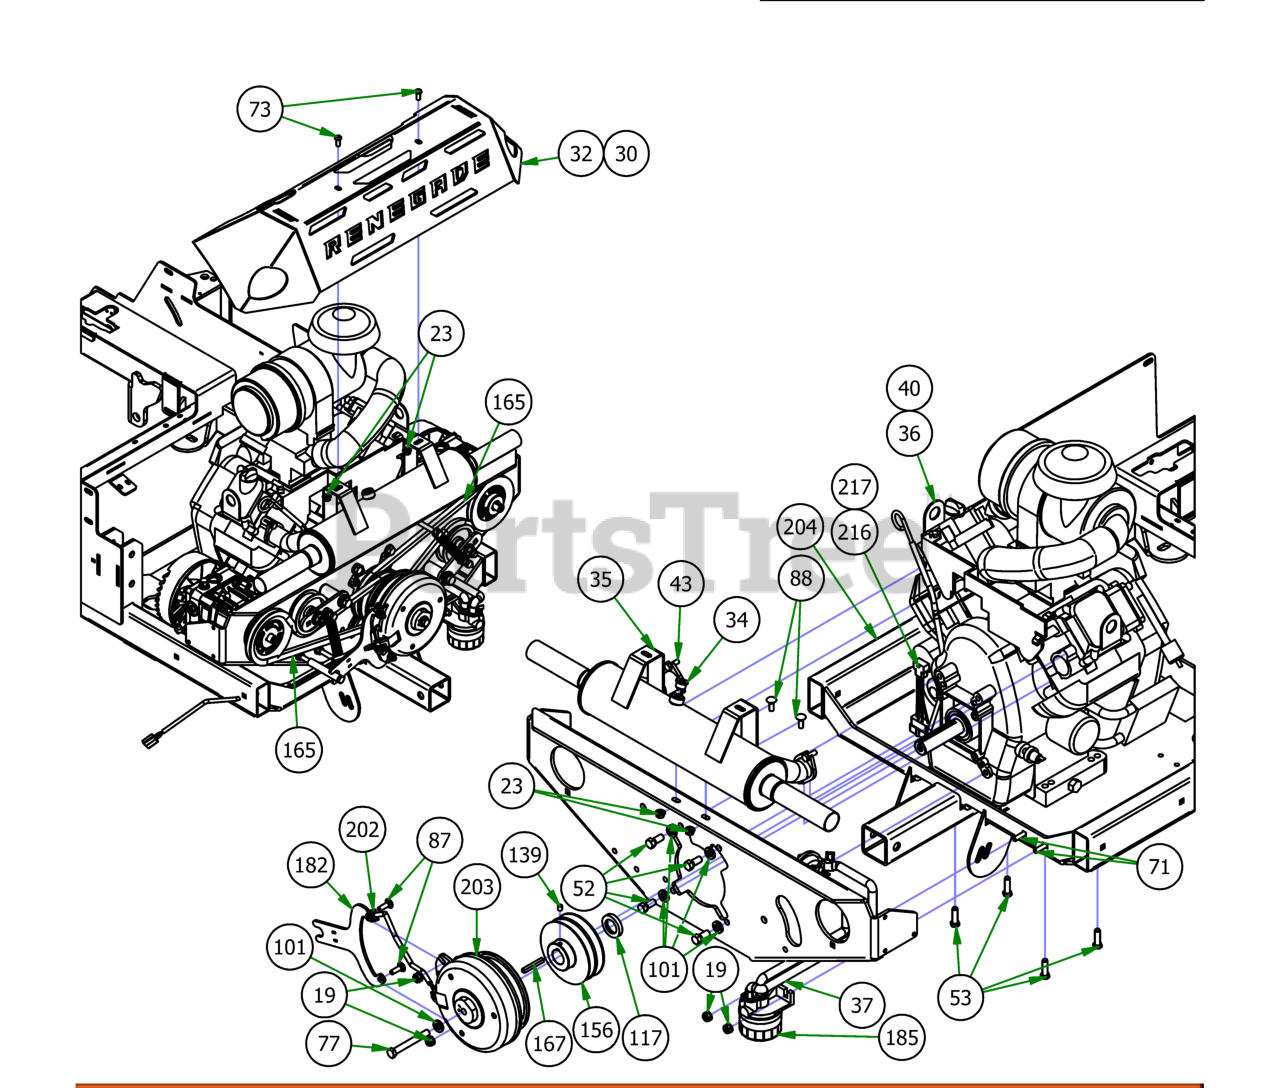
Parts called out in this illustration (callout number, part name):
19	5/16-18 Nylon Flange Nut
23	5/16" Flange Nut
30	Muffler Cover - 2019 Horizontal Gas 37 Vanguard
32	Muffler Cover - 2019 Horizontal Gas 35 Vanguard
34	O2 Sensor Plug
35	2019 Renegade Vanguard 999cc EFI Exhaust
36	Vanguard EFI 37HP 993cc Horizontal Shaft
37	Remote Oil Filter Kit For Vanguard Horizontal
40	35hp Briggs Vanguard
43	Torx Bolt-Exhaust
52	Hex Bolt - UNC (Regular Thread - Inch)
53	3/8-16 x 2 Hex/ Trilobe Horizontal Engine Bolt
71	5/16" x 1 1/4" Carriage Bolt
73	5/16" x 3/4" Button Head Bolt
77	7/16-20 x 3 1/2" Hex Head GR 8 Bolt
87	5/16" x 1" Carriage Bolt
88	5/16" x 7/8" Carriage Bolt
101	7/16" Lock Washer
117	Horizontal Engine Spacer
139	5/16-24 X 3/8 Set Screw
156	Outlaw Renegade Double V Pulley
165	2020 Renegade Pump Belt, 42.99"
167	1/4 x 2 Square key Stock
182	2019 Outlaw Renegade Clutch Bracket
185	Briggs Oil Filter
202	Clutch Pigtail
203	Clutch for Diesel/Vanguard
204	2019 Renegade Gas Frame - Powdercoated
216	2019 Harness Adaptor - 36 Vanguard Carberated
217	2019 Harness Adaptor - Vanguard 37 EFI Vert/Horiz
